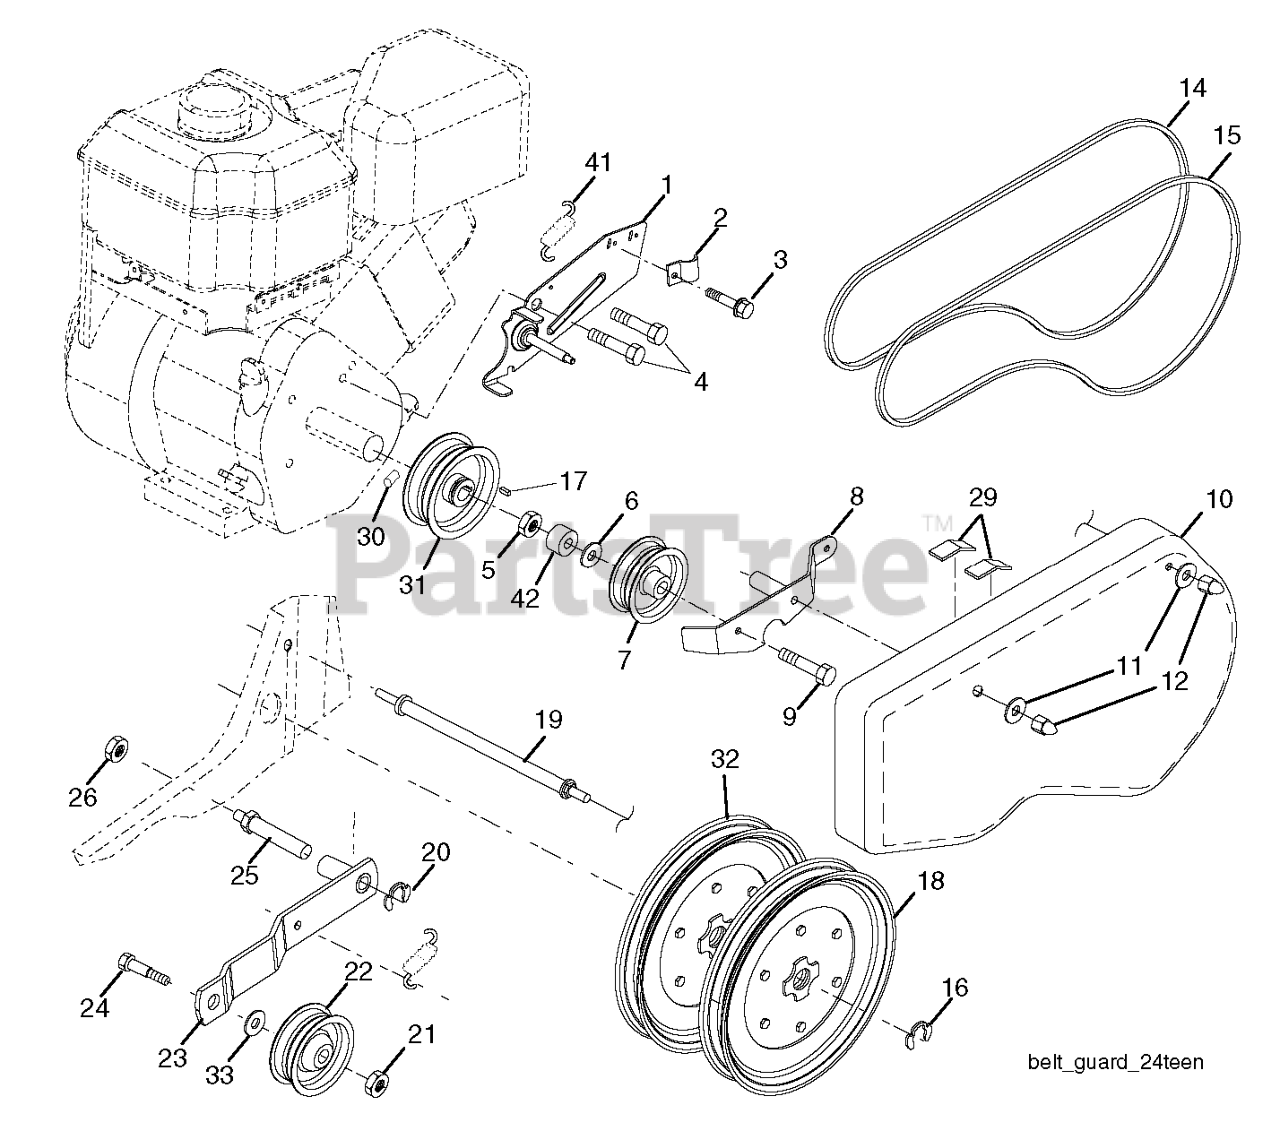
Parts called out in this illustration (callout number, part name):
1	BRACKET,BELTGUARD ASM
2	CLIP.PLATED
3	SCREW.HXTAP.10-24
5	NUT.LOCK.5/16-18
6	BUSHING SPACER.AXLE
7	PULLEY FLAT IDLER
8	ARM.ASM.REV.IDLER.TILLER.BLACK
9	BOLT.FIN HEX 5/16-18UNC X2 1/4
10	GUARD.BELT.TILLER.ORANGE
12	CAP
15	BELT.TILLER.DRIVE
16	RETAINING RING LT
17	KEY.SQ.187 X 1.125
18	SHEAVE,TRANS."D"
19	BOLT.BELT.GUARD
20	KLIP RING TI
21	NUT.LOCK.5/16-18
22	PULLEY.W/SPACER.2.25
23	ARM.ASM.IDLER.PNT
24	HEX BOLT
25	SHAFT.IDLER.TILLER
26	JAM NUT TI
29	PAD IDLER TI
31	ENGINE.PULLEY.TILLER
32	SHEAVE.TRANS
33	WASHER.20X8.5
41	SPRING.EXTENSION
42	SPACER.CONTROL.LEVER
